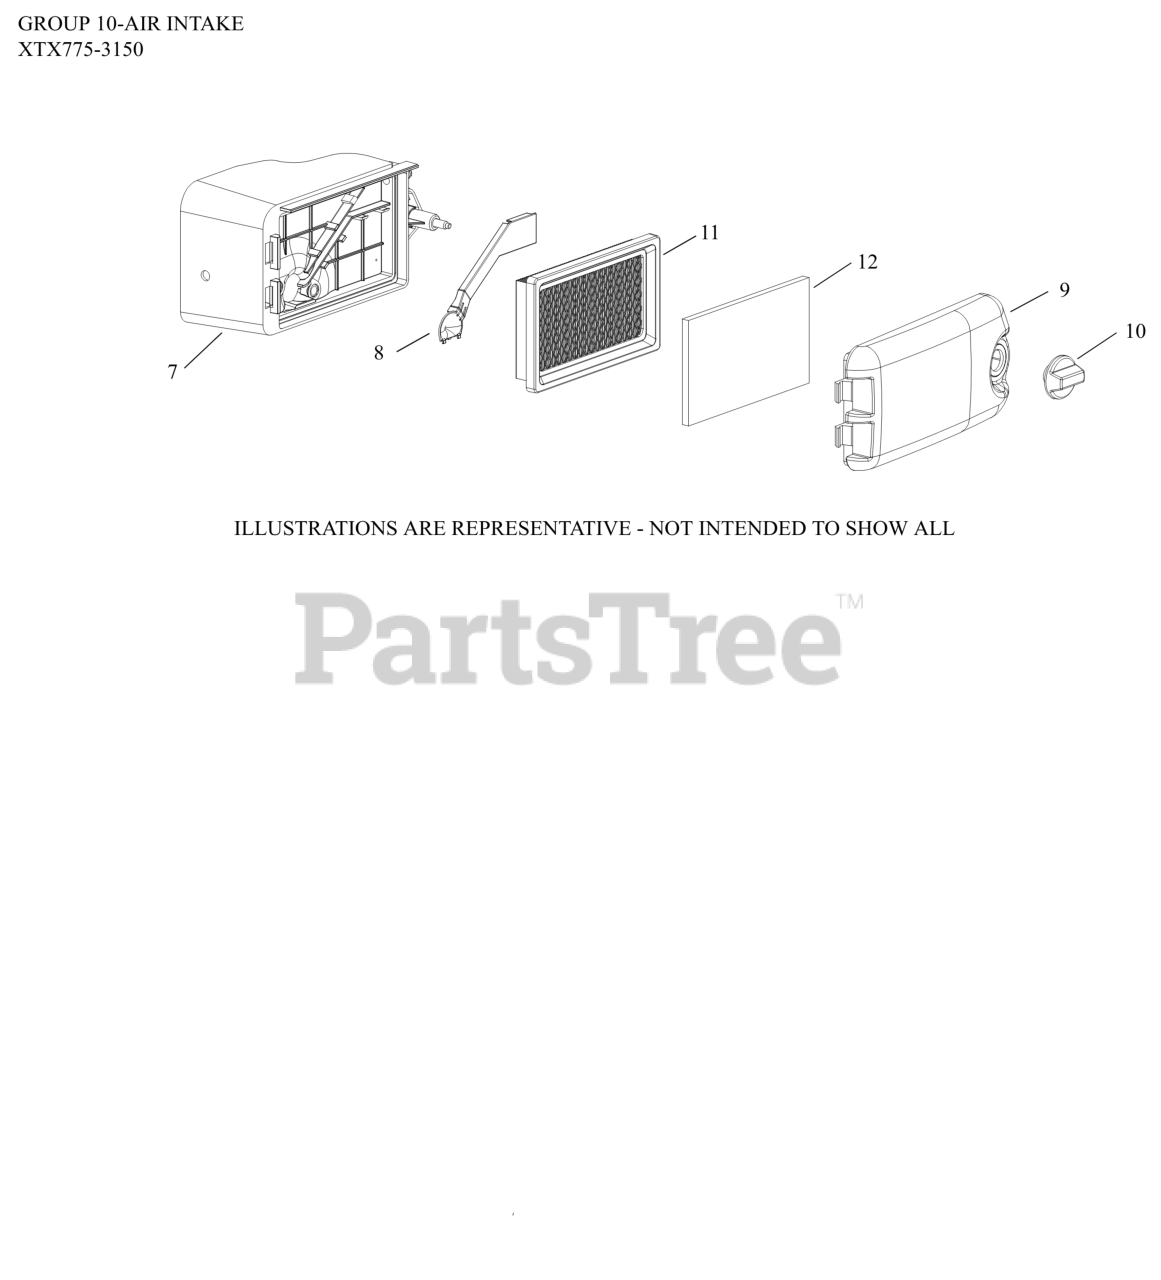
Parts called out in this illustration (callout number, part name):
7	AIR CLEANER BASE-USE 14 094 23-S
8	COVER, A/C BASE (BREATHER GAS)
9	COVER, AIR CLEANER
10	KNOB-USE 14 341 07-S
11	ELEMENT, AIR FILTER
12	ELEMENT, PRE-CLEANER
